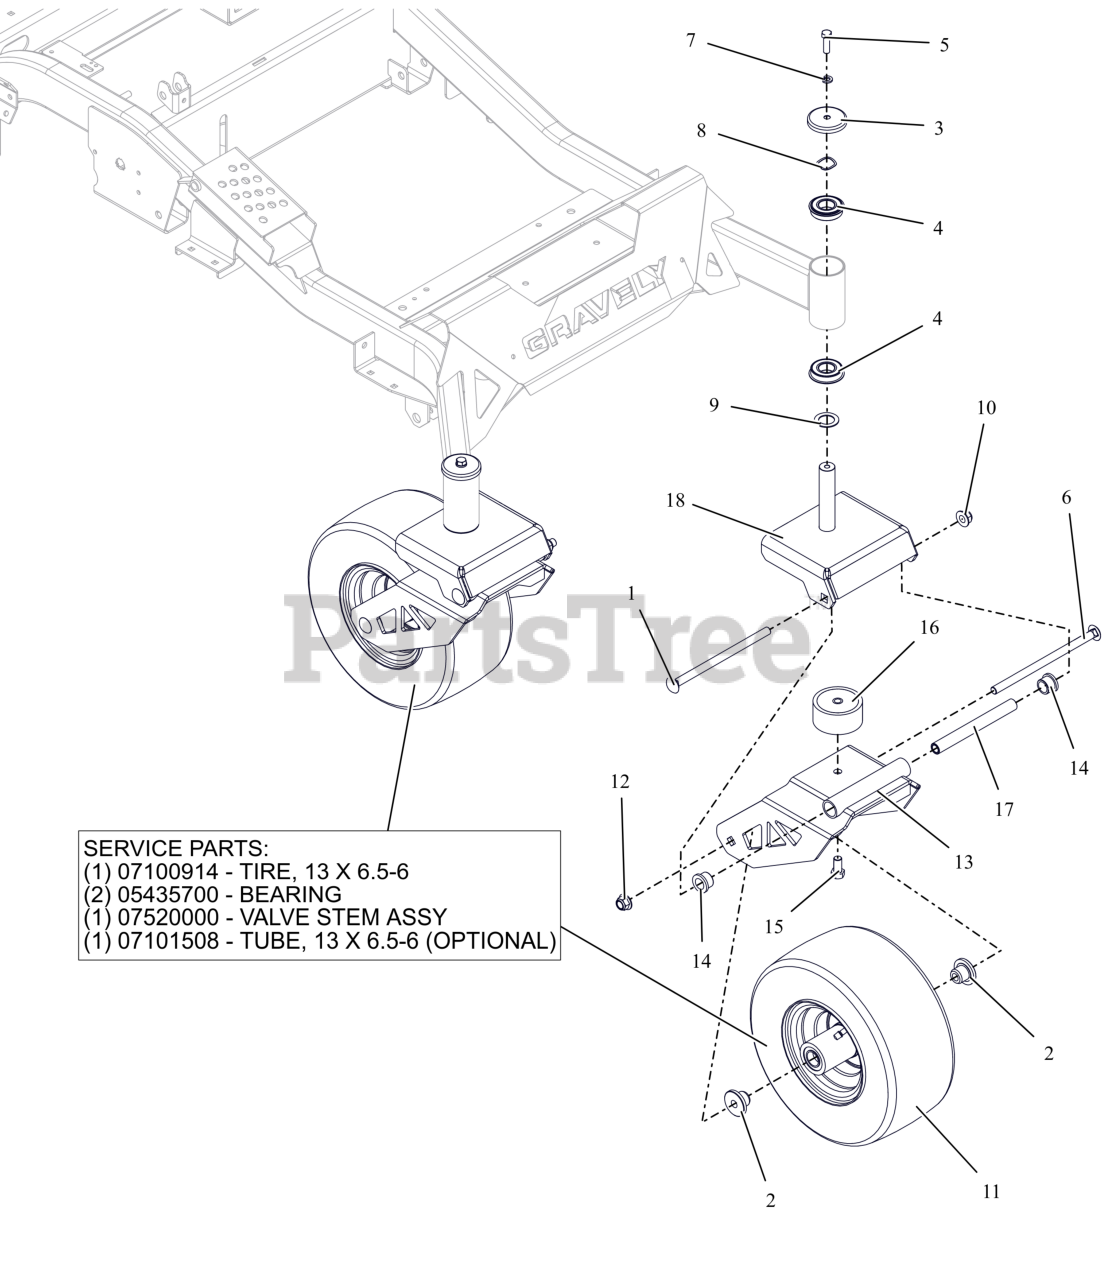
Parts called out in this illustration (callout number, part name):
1	BLT, RHSN .50-13X8.50 G5 ZCC
2	SPACER, FRONT WHEEL
3	SHIELD- AXLE BEARING
4	BEARING, BALL -2.000 OD X 1.000 ID X .5625 W/RING
5	BLT- HEX .38-16X1.25 G5 ZB500
6	BLT-RHSN .50-13X9.00 G5 ZCC NS
7	WSHR-LK-REG .375X.094 ZB500
8	WSHR-WAVE 1.0X1.25X.028 .145FH
9	WSHR-HRD-THRS 1.007X1.542X.062
10	NUT,NYL-FLG .50-13 GF ZCC
11	ASM-TIRE/WHEEL 13X6.50-6
11	TIRE, 13X6.50-6 SMOOTH
11	BRG, 25MM ID X 52MM OD X 15MM
11	VALVE STEM ASS'Y
11	TIRE TUBE 13X6.5-6
12	NUT,NYL-FLG .50-13 GF ZCC
13	WLDMT, LOWER SUSPENSION (RED)
14	BUSHING, FLANGE .75X.75X1.0
15	BLT, HEX .50-13X1.00 G5 ZCC
16	SPCR, RUBBER SUSPENSION
17	ROD, FORK PIVOT
18	WLDMT- UPPER SUSPENSION FORK
